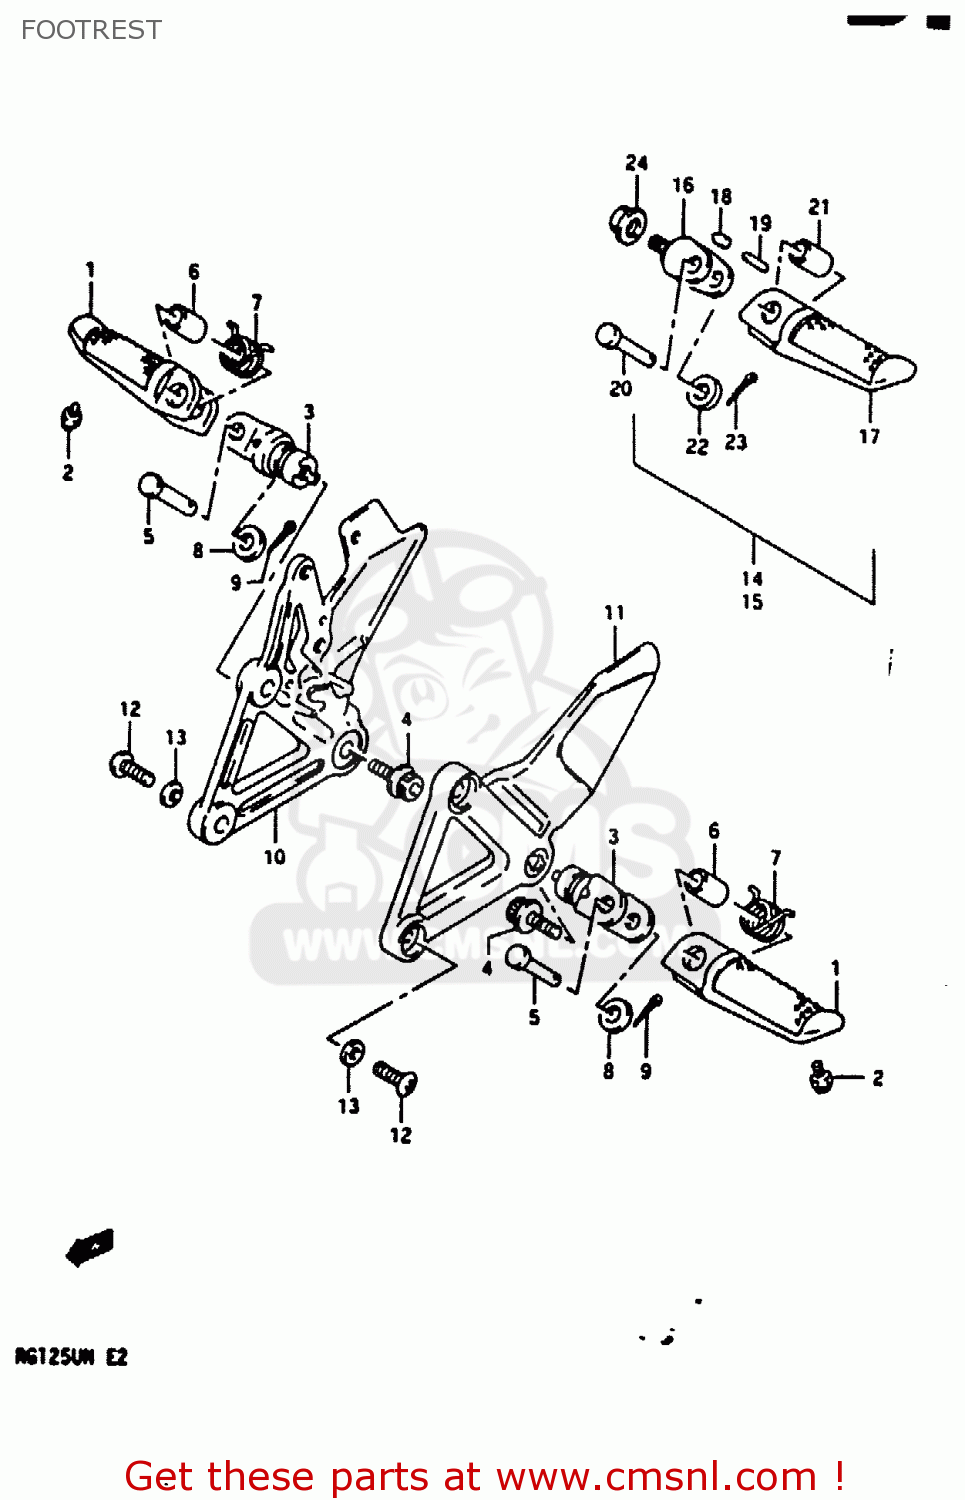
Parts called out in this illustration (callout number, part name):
1	BAR,FR FOOTREST,R
2	BOLT(6X6)
3	HOLDER,FOOTREST
4	BOLT(10X24)
5	PIN
6	SPACER(8.1X12X22)
7	SPRING
8	WASHER
9	PIN 20X15
10	BRACKET,FR FOOTREST,R
11	BRACKET,FR FOOTREST,L
12	BOLT
13	WASHER
14	FOOTREST ASSY, PILLION RH
15	FOOTREST ASSY, PILLION LH
16	HOLDER,PILLION FOOTREST
17	BAR,PILLION FOOTREST R
18	CUSHION,FOOTREST HOLDER
19	ROLLER,FOOTREST HOLDER
20	PIN
21	SPACER(8.1X12X22)
22	WASHER
23	PIN 20X15
24	NUT
